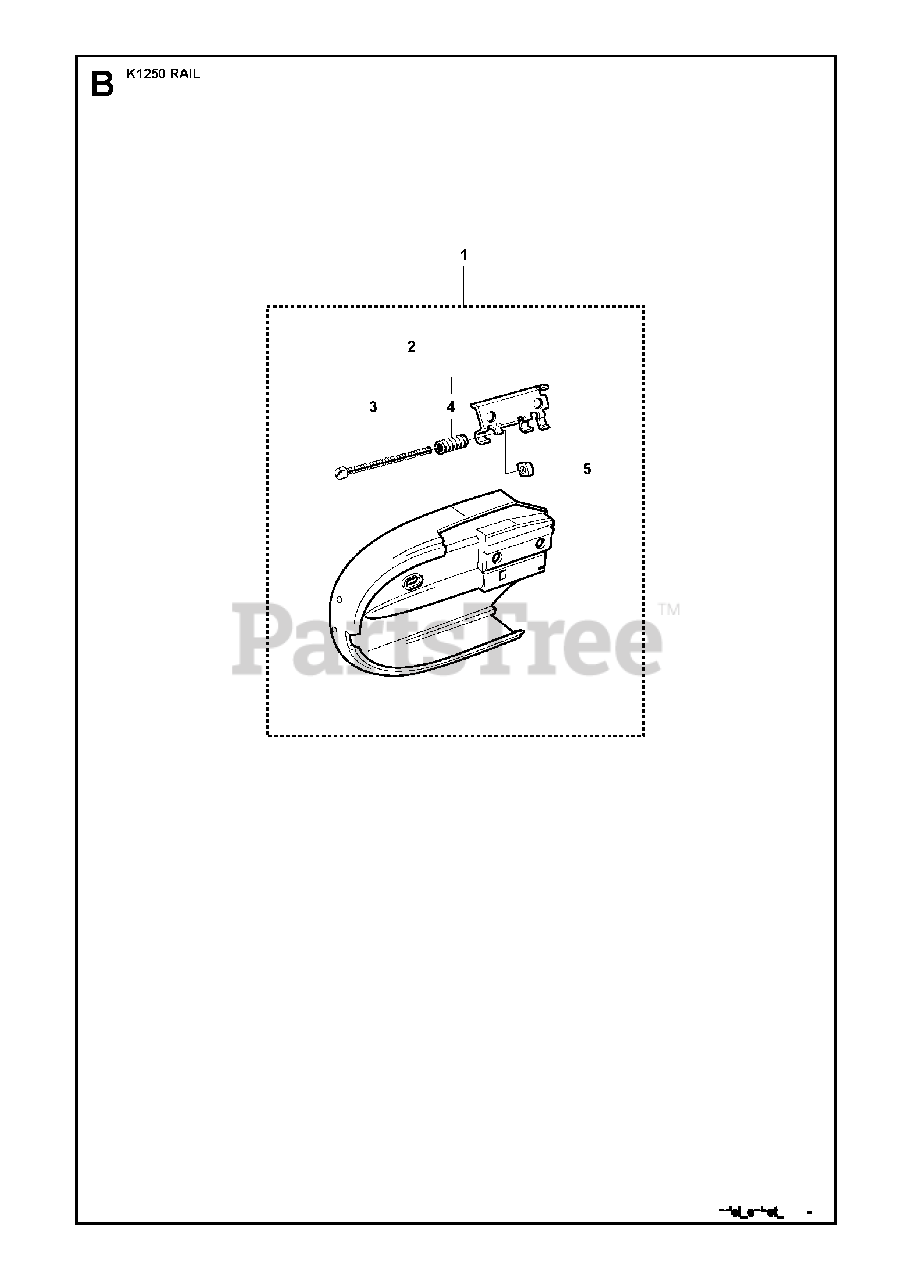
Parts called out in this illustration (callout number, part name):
1	BELT GUARD14" Incl. 2, 5
1	BELT GUARD16" Incl. 2, 5
2	BELT TENSIONER ASSYIncl. 3, 4
4	COMPRESSION SPRING
